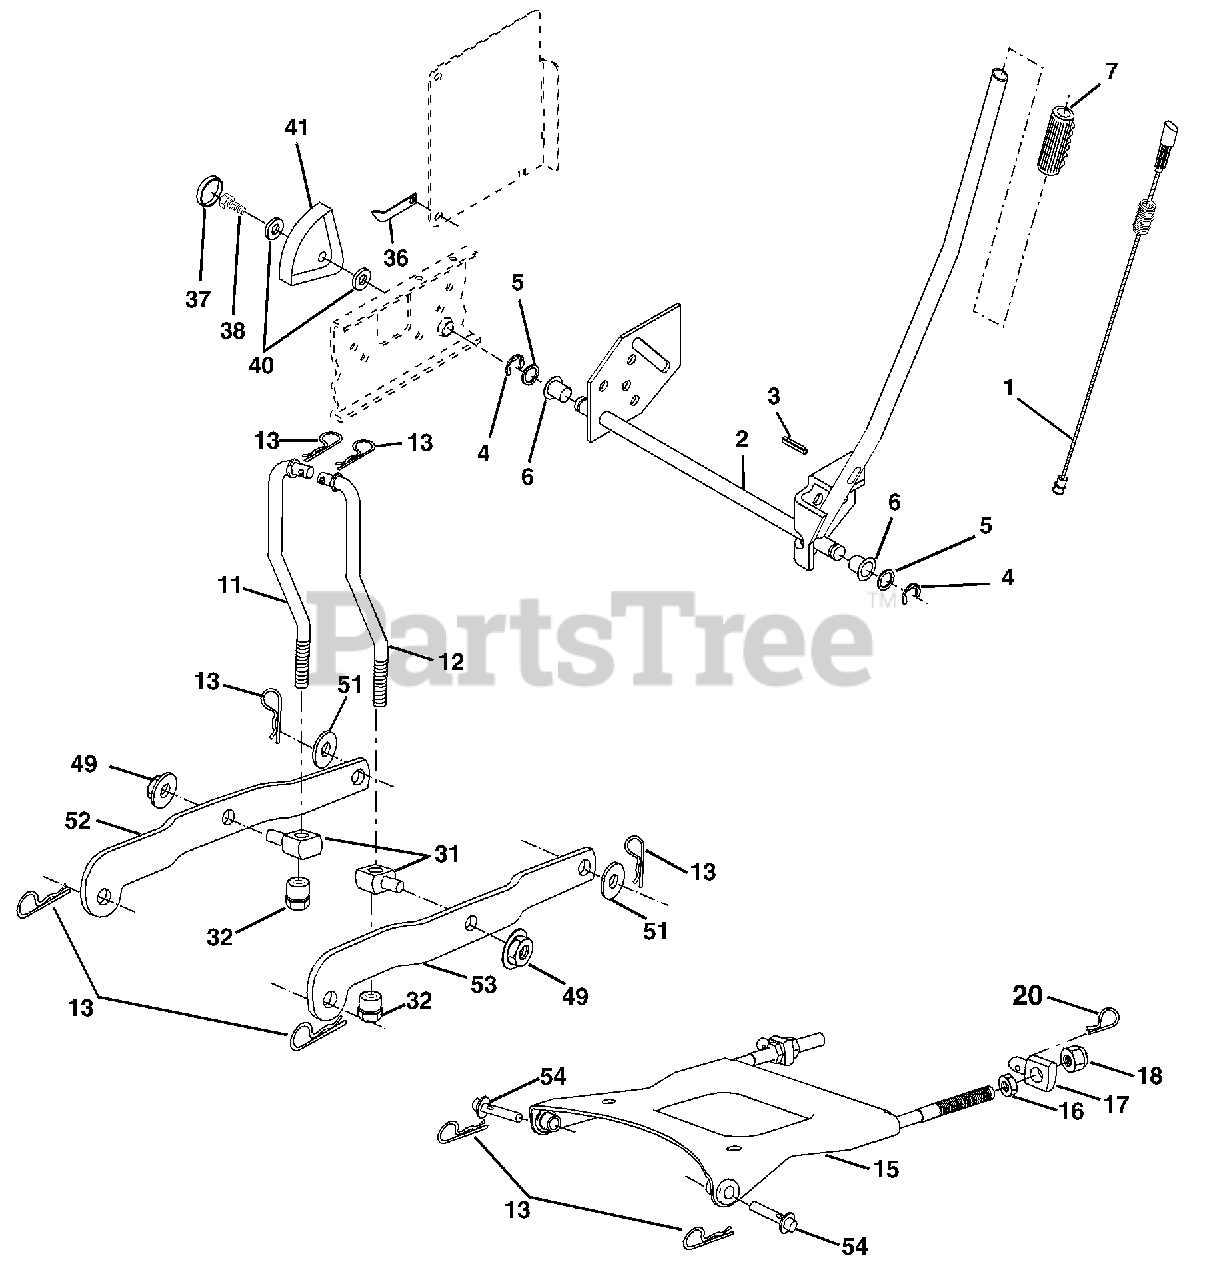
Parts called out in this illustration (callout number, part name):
1	Plunger Assembly
2	Shaft Assembly, Lift
3	Pin, Groove
5	Washer 21/32 x 1 x 21 Ga.
6	Bearing, Nylon
7	Grip, Handle, Fluted
11	Link, Lift, L.H.
12	Link, Lift, R.H.
13	Retainer Spring
15	Plate Asm Suspension Front
16	Nut Hex Jam 1/2-13 unc
17	Trunnion Front Susp.
18	Nut Lock w/Wsh 1/2-13 unc
20	Retainer Spring
31	Trunion Sups. Arm.
32	Nut Lift Link 7/16-20
36	Pointer Height Indicator
37	Plug Hole
38	Screw 5/16-18 x 1
40	Washer 11/32 x 1-1/2 x 10 Ga.
41	Indicator Height Stlt
49	Nut Hex/Large Lock
51	Washer 17/32 x 7/8 x 16 Ga.
52	Arm Suspension Rear LH
53	Arm Suspension Rear RH
54	Pin Flange
